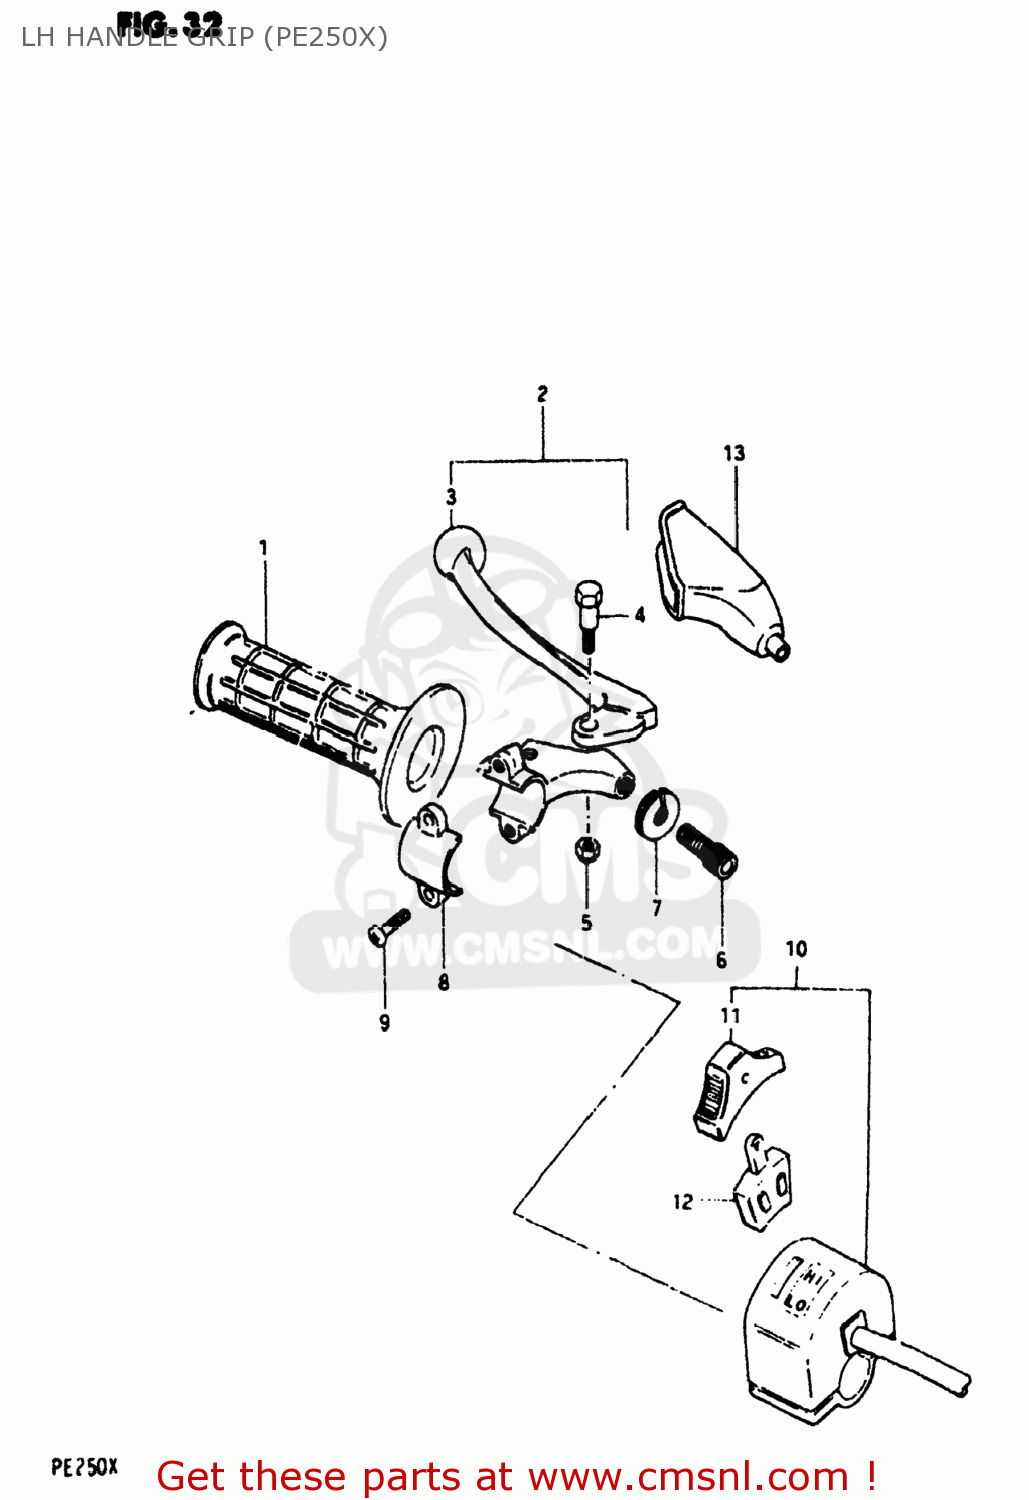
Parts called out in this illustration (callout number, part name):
1	GRIP,LEFT
2	LEVER ASSEMBLY
3	LEVER,CLUTCH
4	BOLT,LEVER
5	NUT 6MM
6	ADJUSTER,CABLE
7	NUT,CABLE ADJUSTER
8	BRACKET,LEVER
9	SCREW
10	SWITCH,DIMMER
11	KNOB,LIGHTING & DIMMER
12	BLOCK,LIGHTING/DIMMER
13	COVER,CLUTCH LEVER
